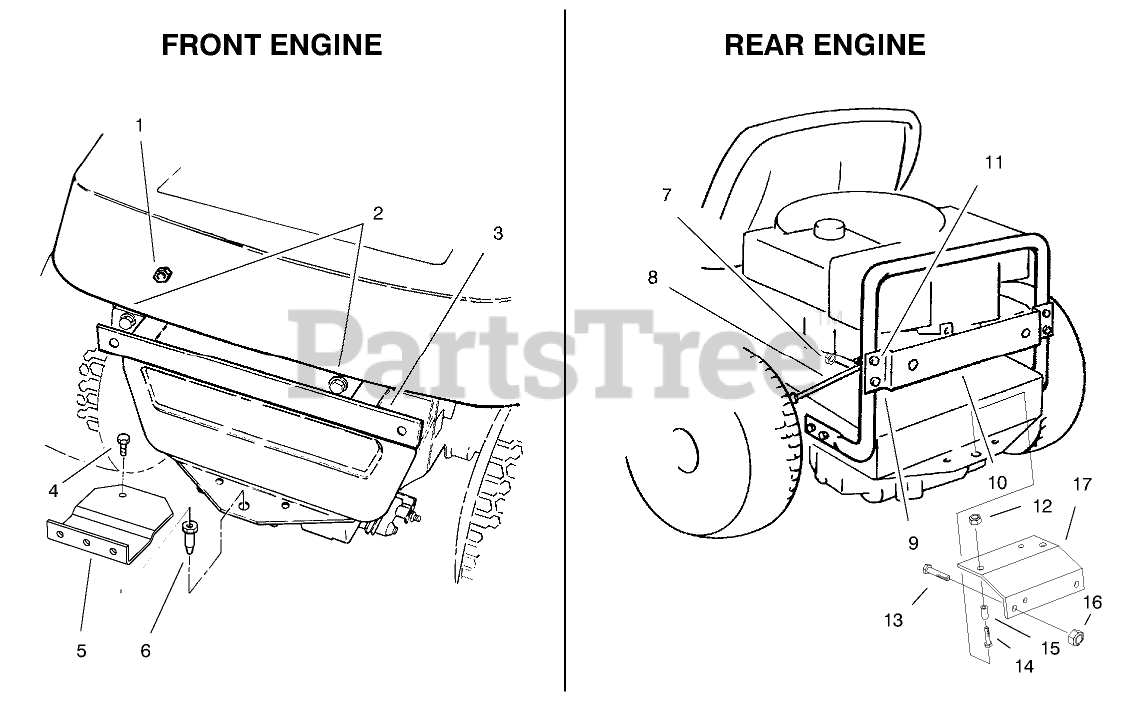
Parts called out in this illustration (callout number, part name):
1	NUT-LOCK, NI
2	SCREW-HH
3	Bracket-Channel
4	SCREW-HH
5	Bracket-Bagger Mounting
6	PIN-MOUNTING, LOWER
7	NUT-LOCK, NI
8	BAGGING KIT BRACE
9	SCREW-HH
10	Plate-Bagging Kit
11	SCREW-HH
12	NUT-LOCK, NI
13	SCREW-HH
14	SCREW-HH
15	Spacer
16	NUT-LOCK, NI
17	Bracket-Hitch
